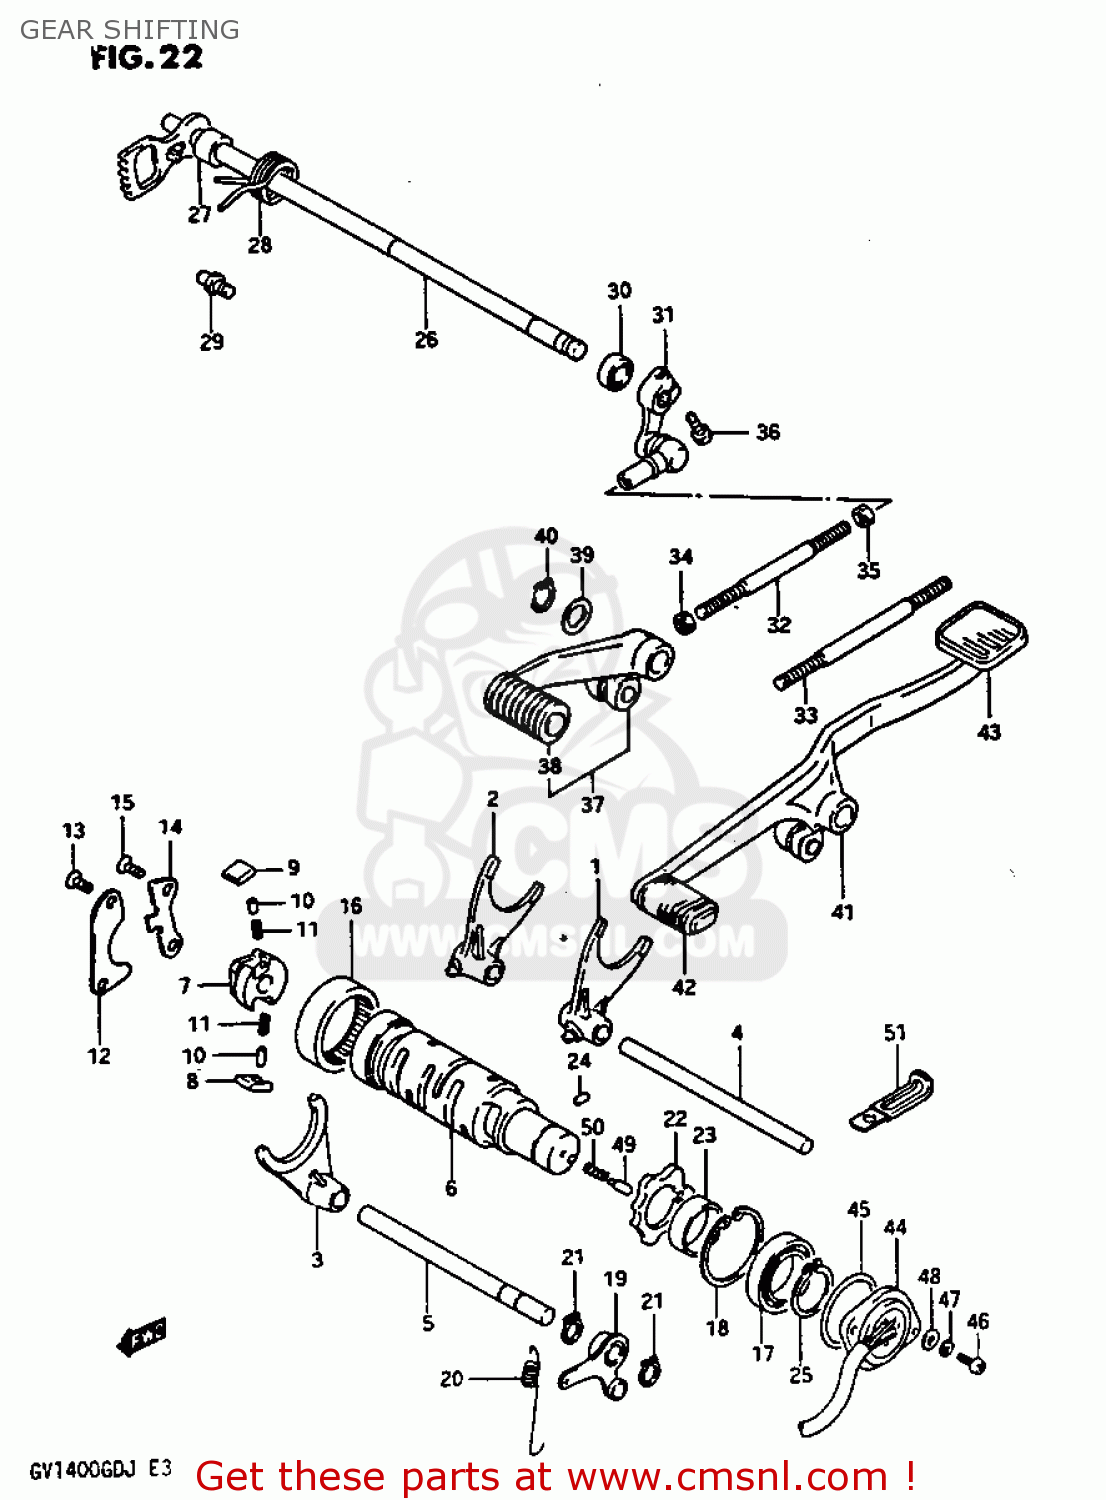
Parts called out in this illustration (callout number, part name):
1	FORK,GEAR SHIFT NO.1
2	FORK,GEAR SHIFT NO.2
3	FORK,GEAR SHIFT NO.3
4	SHAFT,GEAR SHIFT FORK
5	SHAFT,GEAR SHIFT FORK
6	CAM COMP,GEAR SHIFT
7	GEAR,GEARSHIFT CAM DRIVE
8	PAWL,GEAR SHIFT NO.1
9	PAWL,GEAR SHIFT NO.2
10	PIN(5X8)
11	SPRING
12	LIFTER, PAWL
13	SCREW
14	GUIDE,GEAR SHIFTING CABLE
15	SCREW
16	BEARING(43X49X12)
17	BEARING
18	CIRCLIP
19	STOPPER,GEAR SHIFT CAM
20	SPRING
21	CIRCLIP
22	PLATE,GEAR SHIFT CAM STOPPER
23	SPACER
24	PIN 4X6
25	CIRCLIP
26	SHAFT,GEAR SHIFTING
27	SPACER(12X20X15.3)
28	SPRING
29	STOPPER,GEAR SHIFT CAM
30	OIL SEAL
31	ARM,GEAR SHIFT
32	ROD,GEAR SHIFT LINK
33	ROD,GEAR SHIFT LINK NO.2
34	NUT
35	NUT
36	BOLT
37	LEVER ASSEMBLY,GEAR SHIFTING
38	RUBBER,GEAR SHIFT PEDAL
39	WASHER(12.5X20X1)
40	CIRCLIP,12 MM
41	LEVER ASSEMBLY,GEAR SHIFTING
42	RUBBER,PEDAL
43	RUBBER, PEDAL REAR
44	BASE ASSEMBLY,GEAR SHIFT TERMINAL
45	O RING(D:2.4,ID:36.5)
46	SCREW(5X14)
47	LOCK WASHER
48	WASHER
49	PIN(5X15.5)
50	SPRING
51	CLAMP L:35
